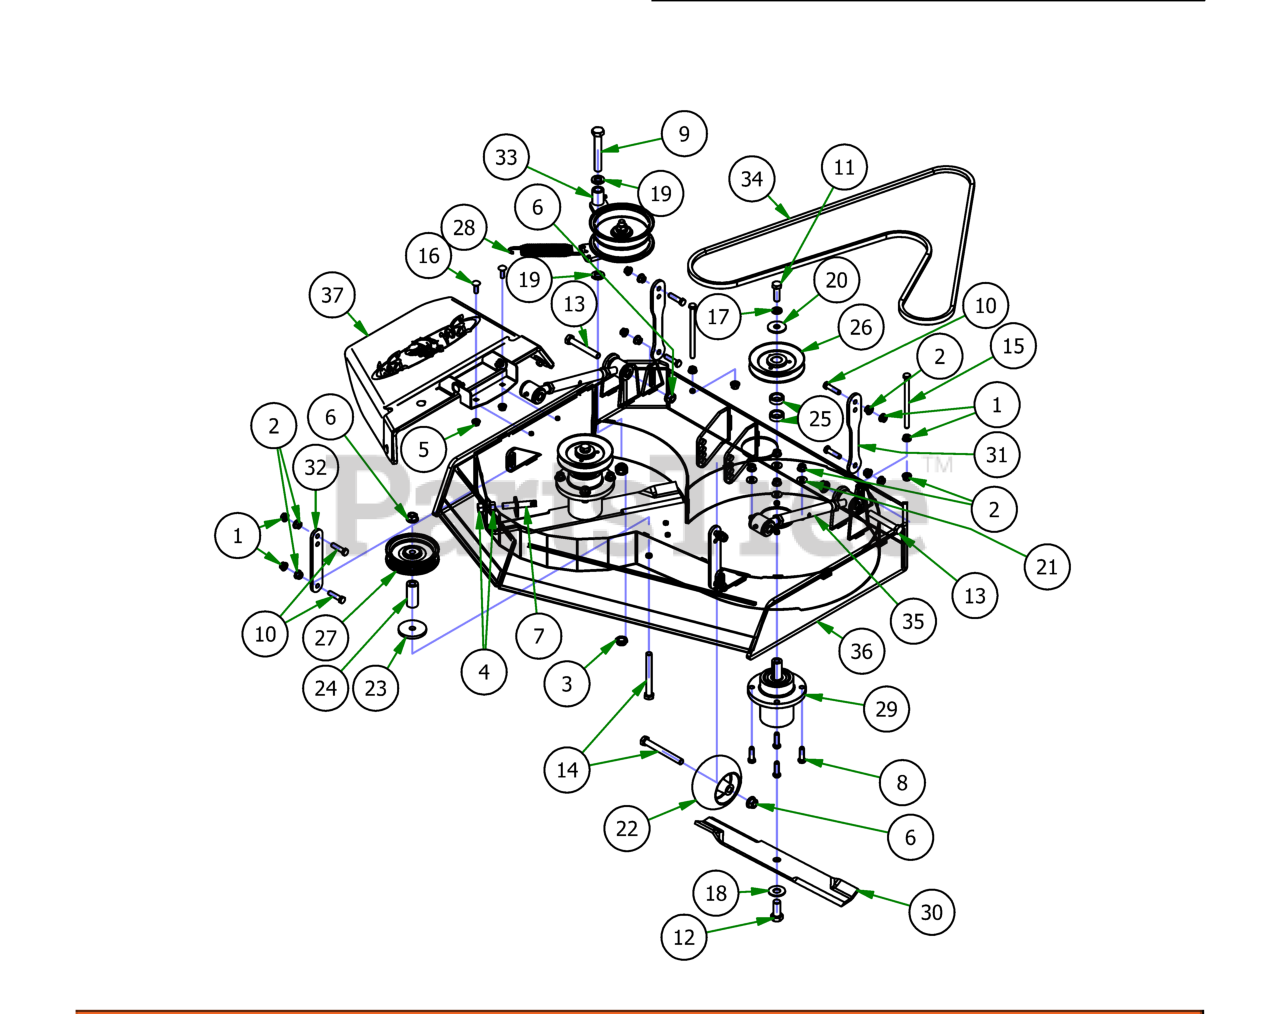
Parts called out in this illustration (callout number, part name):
1	3/8-16 HEX SERRATED FLANGE NUT HARD/ZINC
2	3/8-16 NYLON INSERT FLANGE LOCKNUT (GR.F) ZINC
3	5/8-11 NYLON INSERT JAM LOCKNUT ZINC
4	1/2-13 HEX NUT ZINC
5	5/16-18 NYLON INSERT FLANGE LOCKNUT ZINC
6	1/2-13 NYLON INSERT FLANGE LOCKNUT ZINC
7	All Thread
8	3/8-16 X 1-1/4 HEX CAP SCREW (GR.5) ZINC
9	5/8-11 X 4 HEX CAP SCREW (GR.8) ZINC YELLOW
10	3/8-16 X 1-1/2 HEX CAP SCREW (GR.5) ZINC
11	1/2-20 X 1-1/2 HEX CAP SCREW (GR.5) ZINC
12	5/8-18 X 1-1/2 HEX CAP SCREW (GR.8) ZINC YELLOW
13	1/2-13 X 3-1/2 HEX CAP SCREW (GR.5) ZINC
14	1/2-13 X 4-1/2 HEX CAP SCREW (GR.5) ZINC
15	3/8-16 X 5-1/2 HEX CAP SCREW (GR.5) ZINC
16	5/16-18 X 1 CARRIAGE BOLT (GR.8) ZINC
17	1/2 SPLIT LOCKWASHER (GR.8) ZINC/YELLOW
18	5/8 USS FLAT WASHER (1-3/4" OD) GR.8 ZINC YELLOW
19	.635 ID X 1.120 OD X .140 THICK FLAT WASHER NYLON
20	1/2 BELLEVILLE WASHER (1-5/8 OD X .140 THK) ZINC
21	5/16 USS FLAT WASHER (7/8 OD) ZINC
22	2019 Deck Wheel
23	MZ Deck Idler Spacer
24	2019 Revolt Stationary Idle Spacer
25	36 Deck Spindle Spacer
26	MZ Deck Pulley
27	5 V Idler Pulley 1/2" Bore
28	2009 Deck/Pump Idler Spring
29	36'' Revolt Spindle Assembly
30	52" Deck Fusion Blade
31	2019 Stand-On Rear Deck Hanger
32	2019 Revolt Front Deck Hanger
33	2020 36" Revolt Deck Idler Assembly
34	2020 Walk-Behind 36 Deck Belt
35	2018 Maverick Turnbuckle (Top Link)
37	2020 36 Stand On Discharge Assembly
